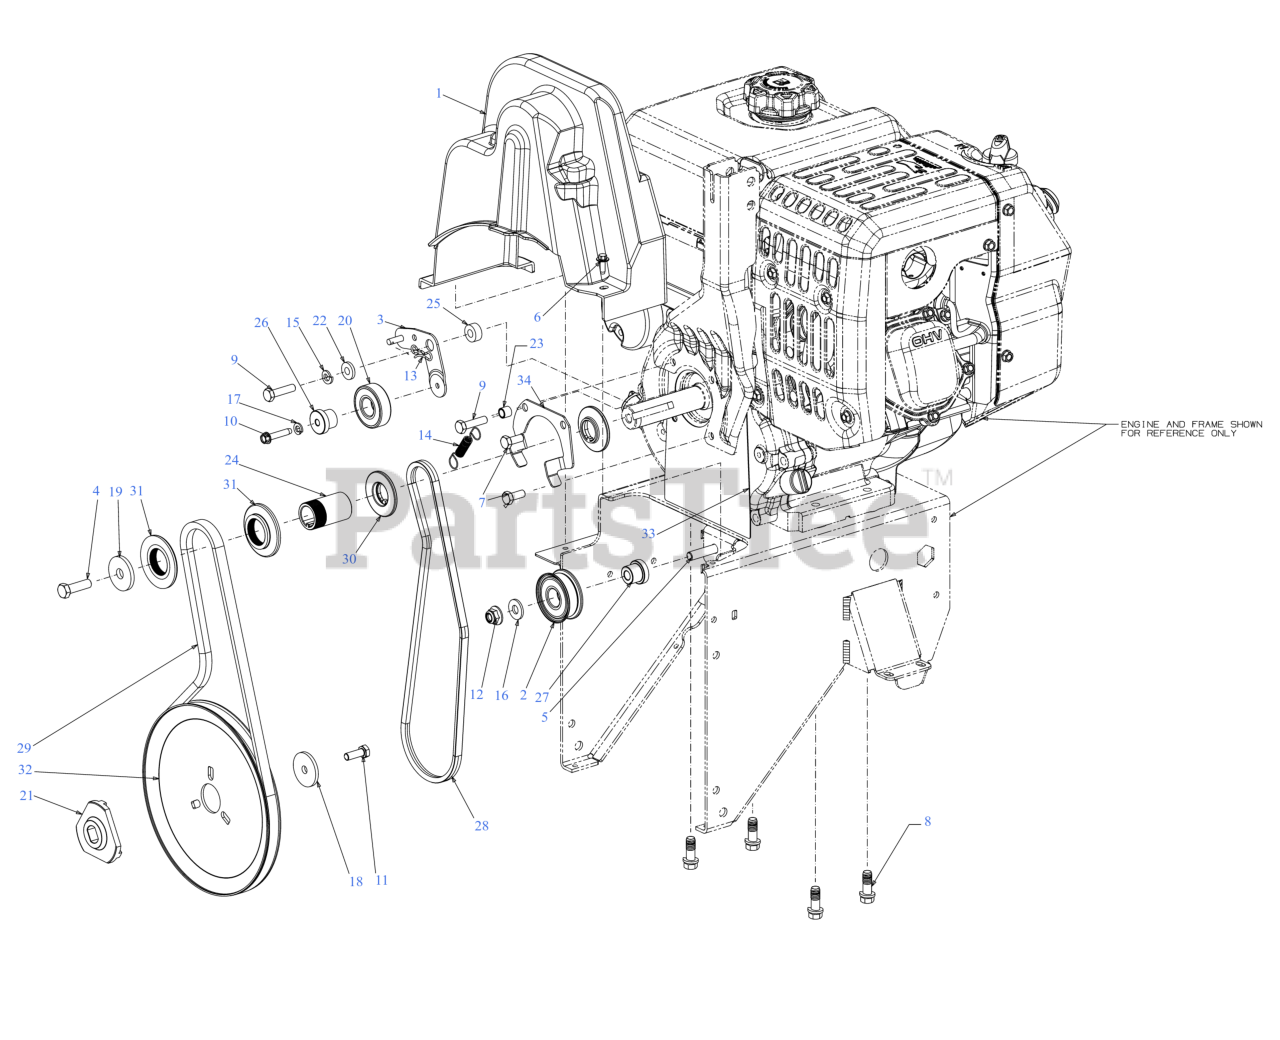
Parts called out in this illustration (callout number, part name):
1	BELT COVER ASSEMBLY
2	IDLER PULLEY ASSEMBLY
3	HYDRO DRIVE IDLER ASSEMBLY
4	SCREW 3/8-24X1.25
5	SCREW 3/8-16 x 1.50
6	SCREW M6-1 x .625
7	SCREW 5/16-24 x .750 GR5
8	SCREW 3/8-16 x 1
9	SCREW 5/16-24 x 1.25 GR5
10	SCREW 1/4-20 x 1.25
11	SCREW 5/16-24 x .875 GR5
13	BOW TIE COTTER PIN 1/4-5/16
14	EXTENSION SPRING .300ID x 2.408LG
15	LOCK WASHER 5/16
16	FLAT WASHER .385X.870X.090
17	LOCK WASHER
18	FLAT WASHER
19	FLAT WASHER .45 x 1.5 x .172 HT
20	BALL BEARING
21	ADAPTER PULLEY .75 DIA W/DD
22	SHOULDER SPACER
24	PULLEY SPACER
25	IDLER BRACKET SPACER .340X.750X.330
26	SHOULDER SPACER
27	SHOULDER SPACER .385 x .785 x .538
28	HYDRO DRIVE BELT
29	AUGER BELT .500 x 41.40
30	HALF PULLEY-3/8 V x 1.7160
31	HALF PULLEY 4L-V x 2.40 OD
32	AUGER PULLEY 8.5 OD
33	ENGINE PLATE (FRONT COVER)
34	BELT KEEPER BRACKET
